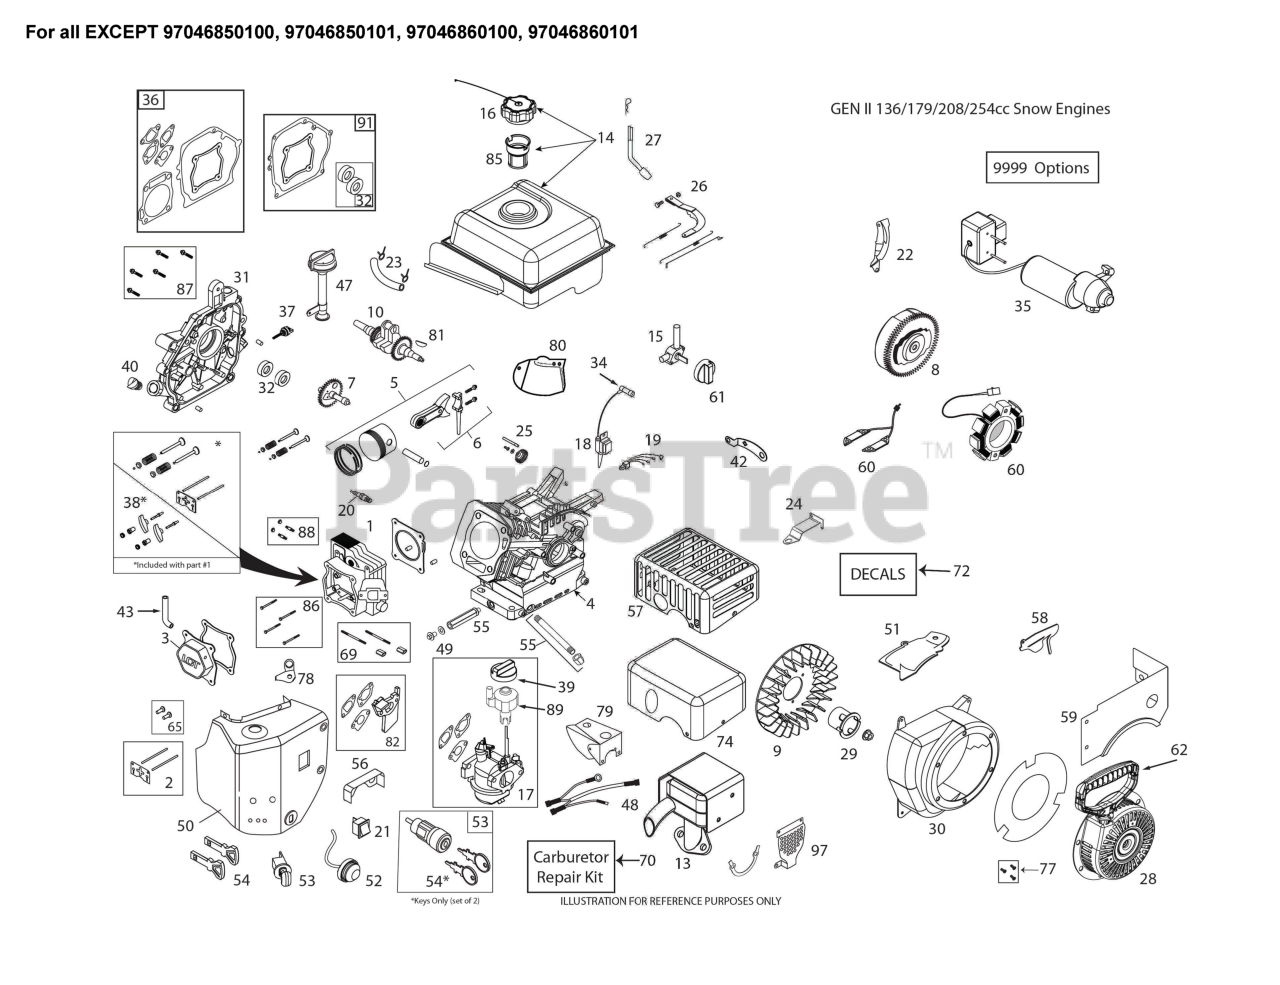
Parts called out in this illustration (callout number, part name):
1	CYLINDR.HEAD.SRV.KIT W/GASKET
2	KIT.PUSH.ROD.SRV(SK208-1001)
3	VALVE COVER ASSEMBLY
4	CYLINDER.ASM.SKSN0001.2
4	CYLINDER LCT.208 GEN II SNO
5	KIT.PISTON.SRV(SK208-1400)
6	KIT.CONNECT.ROD.SRV(SK208-1500
7	KIT.CAMSHAFT.208CC.LCT
8	208CC ELEC START FLYWHEEL
8	FLYWHEEL ELECTRIC START W/6 MA
8	FLYWHL.ASSY.ELECT.(SKSN0405)
9	FLYWHEEL FAN 420586
10	CRNKSHFT-KYD#14.208CCSKSNO8001
13	ASSY.MUFFLER.GENII.SKSN0201.1
13	MUFFLER KIT LCT SKSN2205.1
14	FUEL.TK.ASSY.GENII.SKSN0311.1
15	FUEL.PETCOCK.SNOW(SKSN4900)
16	FUEL CAP OVERSIZED CLICK STYLE
17	CARB.GEN2.W/O.SPACER.LCT.208CC
17	CARBURETTOR L10-1D.W/SP
18	COIL.ING.CDI.HI TEMP.SKSNO416.
18	208CC IGN COIL (STD)
19	CDI.BOX SNOW
20	SPARK.PLUG(2083810)
21	SWITCH.ON/OFF(SKSN-0403)
22	SHIELD.FLYWHEEL.ELEC.STRT.208C
22	SHLD.ELEC.START.FLY(SKSN-0605)
23	KIT.FUEL.HOSE.208CC.SING/STAGE
24	SPEED.CTRL.BRKT.(SKSN0150)
25	GOVENOR.GEARS ASM(SK2082900)
26	CARBURETTOR GOVERNOR LINK.ASM.
27	KIT.GOVERNOR.CRANK(SK208-3100)
28	RECOIL.STRT.ROUND(BLK) SNOW
29	STRTER.CUP(NON-SLOT)SKSN0601.2
30	BLOWER HOUSING ASSY
30	BLOWER.HOUSING.ELEC.START.LCT
31	CRANKCASE.CVR.PRESS.IN.HI-OIL.
31	COVER.CRANKCASE.LCT.HIGH.OIL.F
31	COVER CRANKCASE.LCT.SK2083605
32	SEAL KIT (2 PCS)
34	SPARK.PLUG.BOOT.SNW,SKSN4691.1
35	STARTER 230C EL START.LCT SKSN
35	ELEC.START.GEN2.SKSN0451.1
35	EURO.230V.ELECT.ST(SKSN0452.1)
36	GASKET.KIT.208CC(SK2084300.1)
37	DIPSTICK SMALL
38	ROCKER ARM KIT
39	CHOKE.KNOW.SNOW(SKSN4500)
40	NON REMOVABLE PLUG
43	TUBE.BREATHER.LCT.208
47	TUBE ASSY HIGH OIL-FILL
48	WIRE.HARNESS.SNOW
48	HARNESS WIRE. W/O OFF/ON SWITC
49	KIT.OIL.DRAIN.PLUG(SK2089911
50	HEATER.BOX.ASY-GEN2
50	BOX HEATER.W/O OFF/ON SWITCH.L
51	SHIELD.CYLINGER.LCT.SKSN0608.1
52	PRIMER.BULB.WITH HOSE (SNOW)
53	SWITH.KEY.ASSEM.SNOW.SINGLE.ST
54	KEY SET(2 KEYS) SKSN0407.1
55	OIL PIPE DRAIN LCT 254
55	EXTENDED OIL DRAIN TUBE
56	SHIELD.VAPOR.SNOW
57	SHIELD.MUFFLER.CE.COMPLIANT
58	GOVERNOR.LINK.SHIELD PLATE
58	SHIELD GOVENOR & CARB - COMPOS
59	FUEL.TNK.SKRT.GENII.SKSN0103.1
60	CHARGING.COIL(ELEC)SKSN0406.1
60	208CC 60W ALTERNATOR
61	FUEL KNOB-SNOW
62	STARTER.GRIP.SNOW.LCT.SKSN0603
62	HANDLE.RECOIL.DELUXE.LCT
65	TAPPET.KIT.LCT.208CC
69	CARB.STUDS & COUPLING KIT.SNOW
70	CARBURETOR.REPAIR KIT.LCT.
70	CARB.REPAIR.KIT.LCT.SK9900.2
72	KIT.ENGINE.DECAL.208CC.LCT.SK1
72	ARIENS 414 SNOW DECAL KIT
74	SHIELD.MUFFLER.CE.COMPLIANT
74	MUFFLER GUARD.EUR./LCT.SKSN220
77	BOLT.KIT.RECOIL.LCT.ALL.ENGINE
79	COVER.CARBURETOR.SNOW
81	KEYS.FLYWHEEL.208/414CC.5PACK
82	SPACER.CARBURETOR.208CC.LCT
85	STRAINER.FUEL.TANK.LCT.208CC
86	KIT.BOLT.CYLINDER.HEAD.(4PC)
86	BOLT KIT.CYLINDER HEAD.LCT(4)1
87	KIT.BOLT.CRANKCASE.COVER.6PC
88	STUD.MUFFLER.KIT.LCT
89	KNOB LCT.SKSN5325.1 SPEED
91	COVER CRANKCASE GASKET
97	MUFFLE MANIFOLD GUARD.LCT
9999	GUARD.MUFFLER.MANIFOLD.LCT
9999	STARTER SCREW.STARTER SWITCH B
9999	HIGH.ALTITUDE.JET 6,000FT
9999	KIT.BOLT.LCT.SK9990.1
